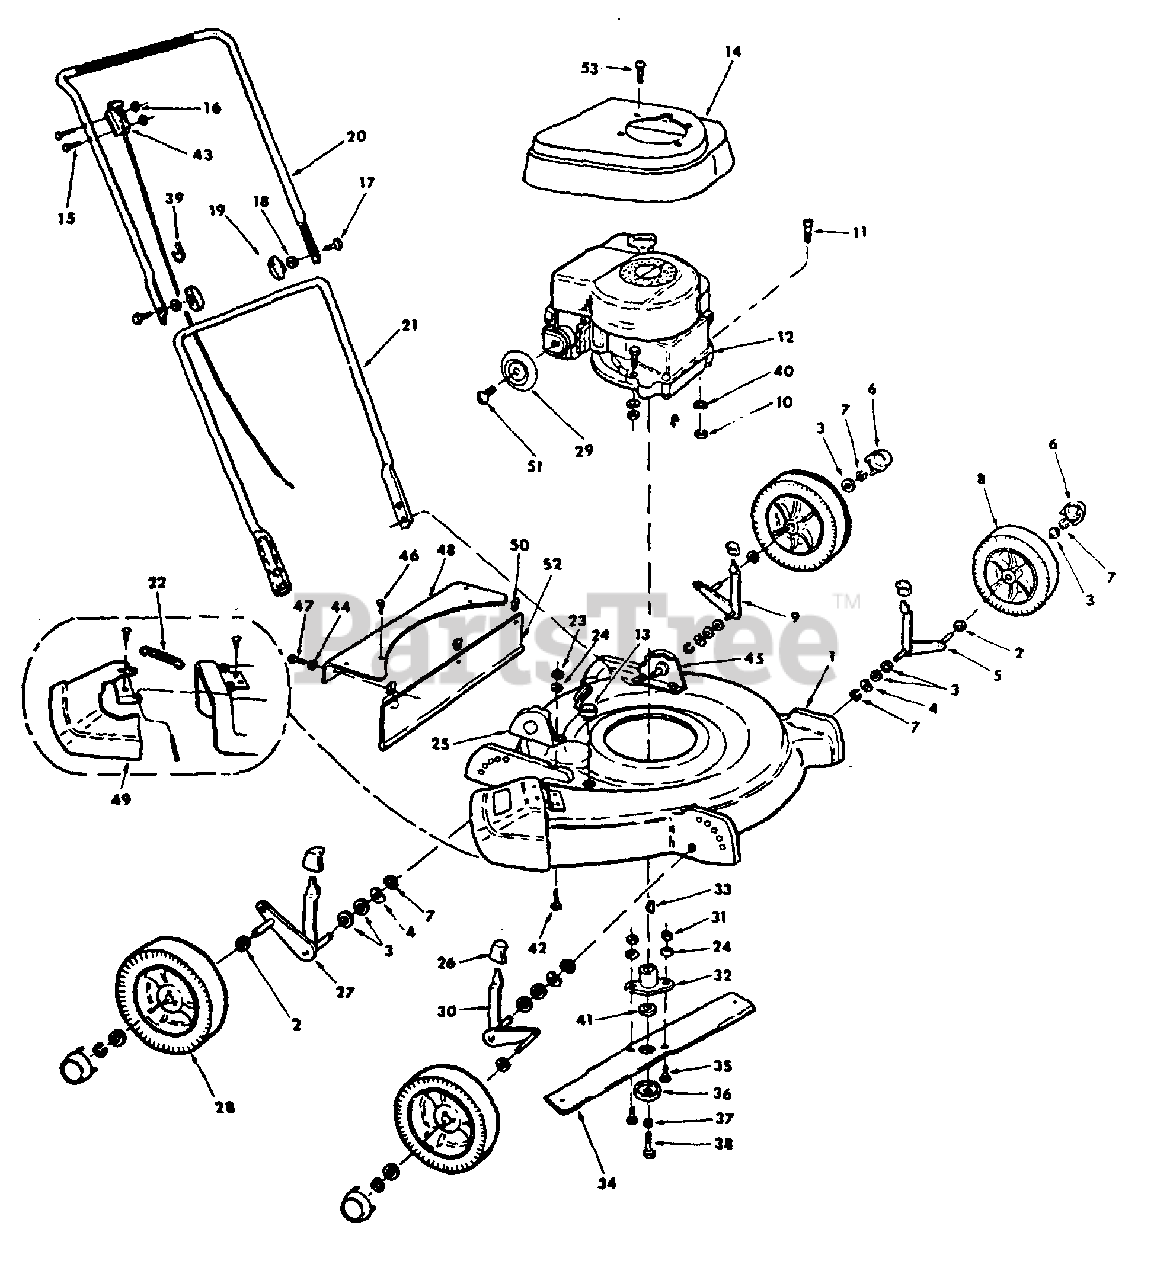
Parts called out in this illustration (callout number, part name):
1	HOUSING ASSY. BLADE
2	WASHER, 1/2 X 1 X .125
3	WASHER, 1/2 X 1 X .030
4	WASHER, WAVE
5	AXLE, FRONT LH
7	RING, RETAINING
8	WHEEL AND TIRE ASSY FRONT
9	AXLE, REAR LH
10	NUT, 5/16-18 END HEX
11	SCREW, 5/16-18 X 1-1/2 ZND HEX-HD CAP
12	ENGINE, 3 HP.
13	CAP, WASHOUT PORT
14	SHROUD, ENGINE
15	SCREW, 10-32 X 1-3/8 HEX-HD MACH
16	NUT, 10-32 HEX. LOCK
17	SCREW, 5/16-1B X 1-3/4 HEX.
18	WASHER, 5/16 REG LOCK
19	KNOB, HANDLE
20	HANDLE, UPPER
21	HANDLE, LOWER
22	SPRING, DEFLECTOR
23	NUT, 1/4-20 PHC HEX, LOCK
24	WASHER, 1/4 REG LOCK
25	BRACKET AND PIN ASSY, RH
26	KNOB, ADJUST LEVER
27	AXLE, REAR RH
28	WHEEL AND TIRE ASSY, REAR
29	DEFLECTOR, MUFFLER
30	AXLE, FRONT RH
31	NUT, 1/4-20 HEX.
32	ADAPTER, BLADE
33	KEY, WOODRUFF - ENGINE CRANK
34	BLADE, 20 l N.
35	SCREW, 1/4-20 X 3/4 HEX-HD CAP
36	WASHER, BLADE 70 CRANKSHAFT
37	WASHER, 3/8 REG LOCK
38	SCREW, 3/8-24 X 1-1/8 HEX-HD CAP
39	CLIP, CABLE
40	WASHER, .344 X .625 X 054 END
41	SPACER, ANTI FLIP BRACKET
42	SCREW, 1/4-20 X 5/8 SQ-NK CRG
43	CONTROL ASSY, THROTTLE
44	WASHER, .219 X .75 X .054
45	BRACKET AND PIN ASSY, LH
46	SCREW, 10-24 X 1/2 HEX WASHER-HD TAP
47	SCREW, 10-12 X 7/8 SHEET METAL
48	COVER, DECK
49	DEFLECTOR ASSY, MISSILE
50	NUT, U-SHAPED SPRING
51	SCREW, 8-32 X 1-1/8 HEX-HD TAP
52	DEFLECTOR, REAR
53	SCREW, 8-15 TRUSS-HD
